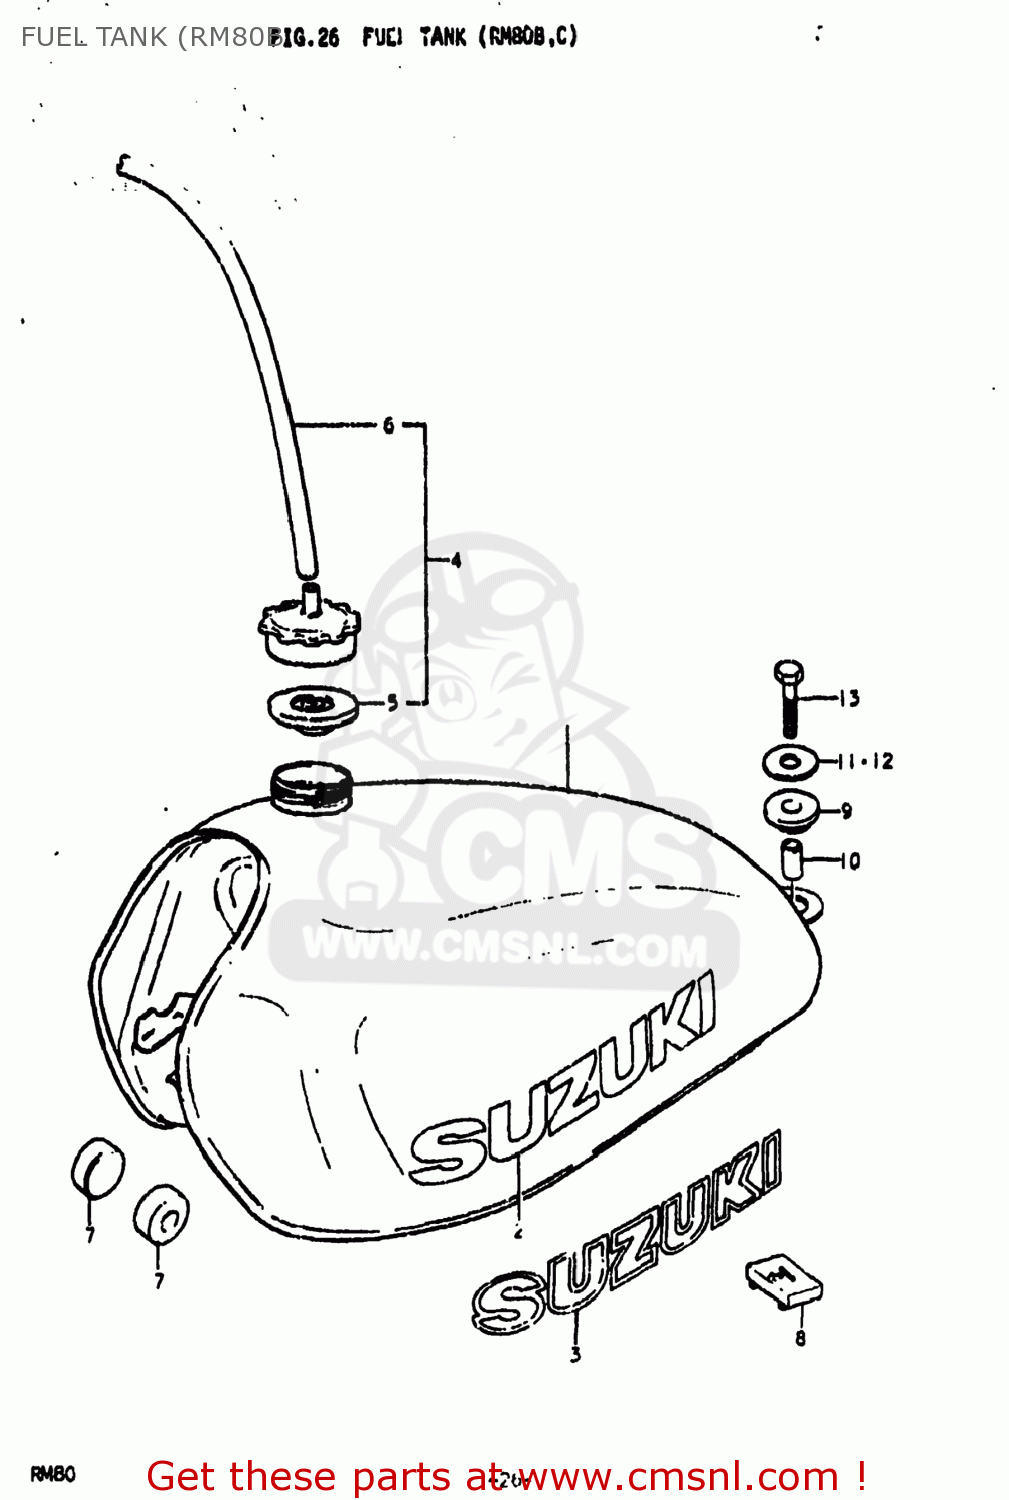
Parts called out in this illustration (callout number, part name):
1	TANK ASSEMBLY,FUEL
2	EMBLEM
3	EMBLEM
4	CAP ASSY,FUEL TANK FILLER
5	GASKET,FUEL TANK CAP (NAS)
6	HOSE
7	CUSHION
8	CUSHION,FUEL TANK
9	CUSHION
10	SPACER (8X12X15)
11	WASHER
12	WASHER (8.5X29X1.6)
13	BOLT (8X30)
